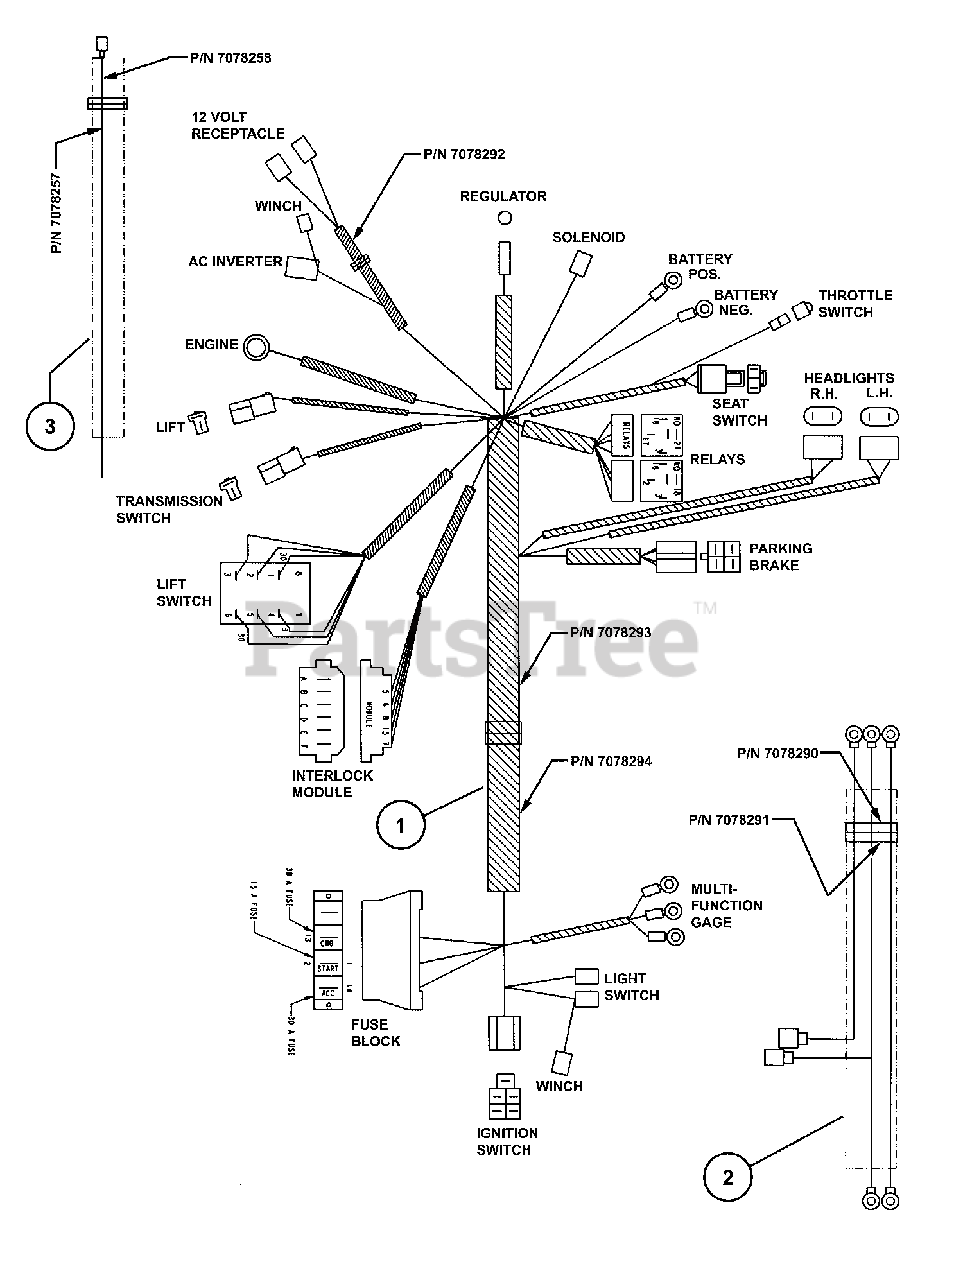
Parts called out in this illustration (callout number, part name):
1	WIRING HARNESS, UV2, Main
2	WIRING HARNESS, UV2, Speed/Fuel
3	WIRING HARNESS, UV2, Tachometer
